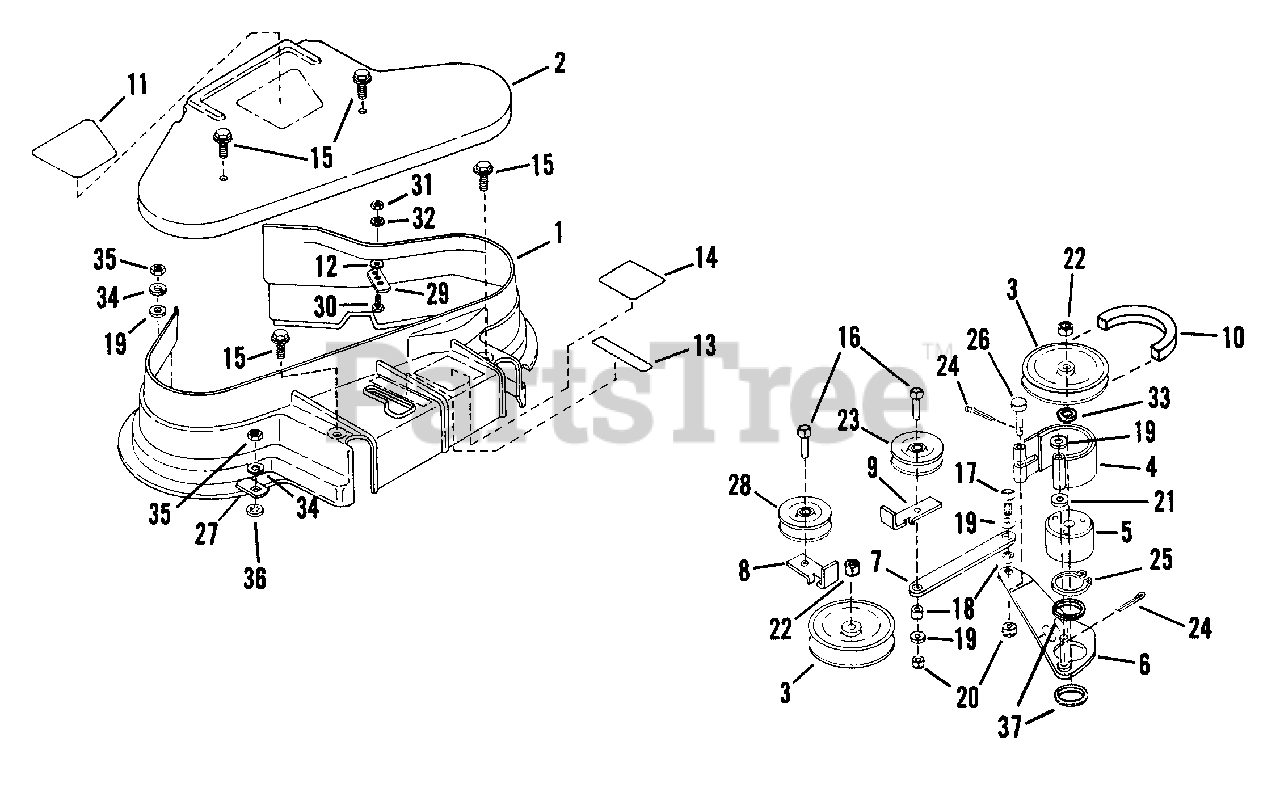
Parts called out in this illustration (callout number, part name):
1	ASSEMBLY, 41" Cover-Bottom & Decal
2	ASSEMBLY, 41" Cover-Top & Decal
3	PULLEY, 5" O.D.
4	BAND, Brake Assembly
5	BRAKE DRUM
6	BRAKE ARM ASSEMBLY
8	GUIDE, Belt
9	RESTRICTOR
10	BELT, AA105
11	DECAL, Caution
12	WASHER, 1/4 Flat
13	DECAL, Blade ON-OFF
14	DECAL, Brake Operation
15	SCREW, 1/4-28x5/8 Hex Head Self-Tapping
16	SCREW, 3/8-24x1 3/4 Hex Head Cap
17	SCREW, 3/8-24x3/4 Hex Head Cap
18	SPACER
19	WASHER, 3/8" Flat
20	NUT, 3/8-24 Hex Lock
21	SPACER
22	NUT, 3/4-16 Hex Jam Lock
23	PULLEY, Idler
24	COTTER PIN, 3/32x3/4
25	RING, 2" External Retaining
26	PIN, 1/4 Clevis
27	CLIP
28	PULLEY, Idler
29	GUIDE, Belt
30	SCREW, 1/4-20x1/2 Hex Head Cap
31	NUT, 1/4-20 Hex
32	WASHER, 1/4 Internal Tooth Lock
33	WASHER, 3/4 Flat
34	WASHER, 3/8 Split Lock
35	NUT, 3/8-16 Hex
36	RETAINER, 3/8 Bolt
37	WASHER, 2" I.D.
